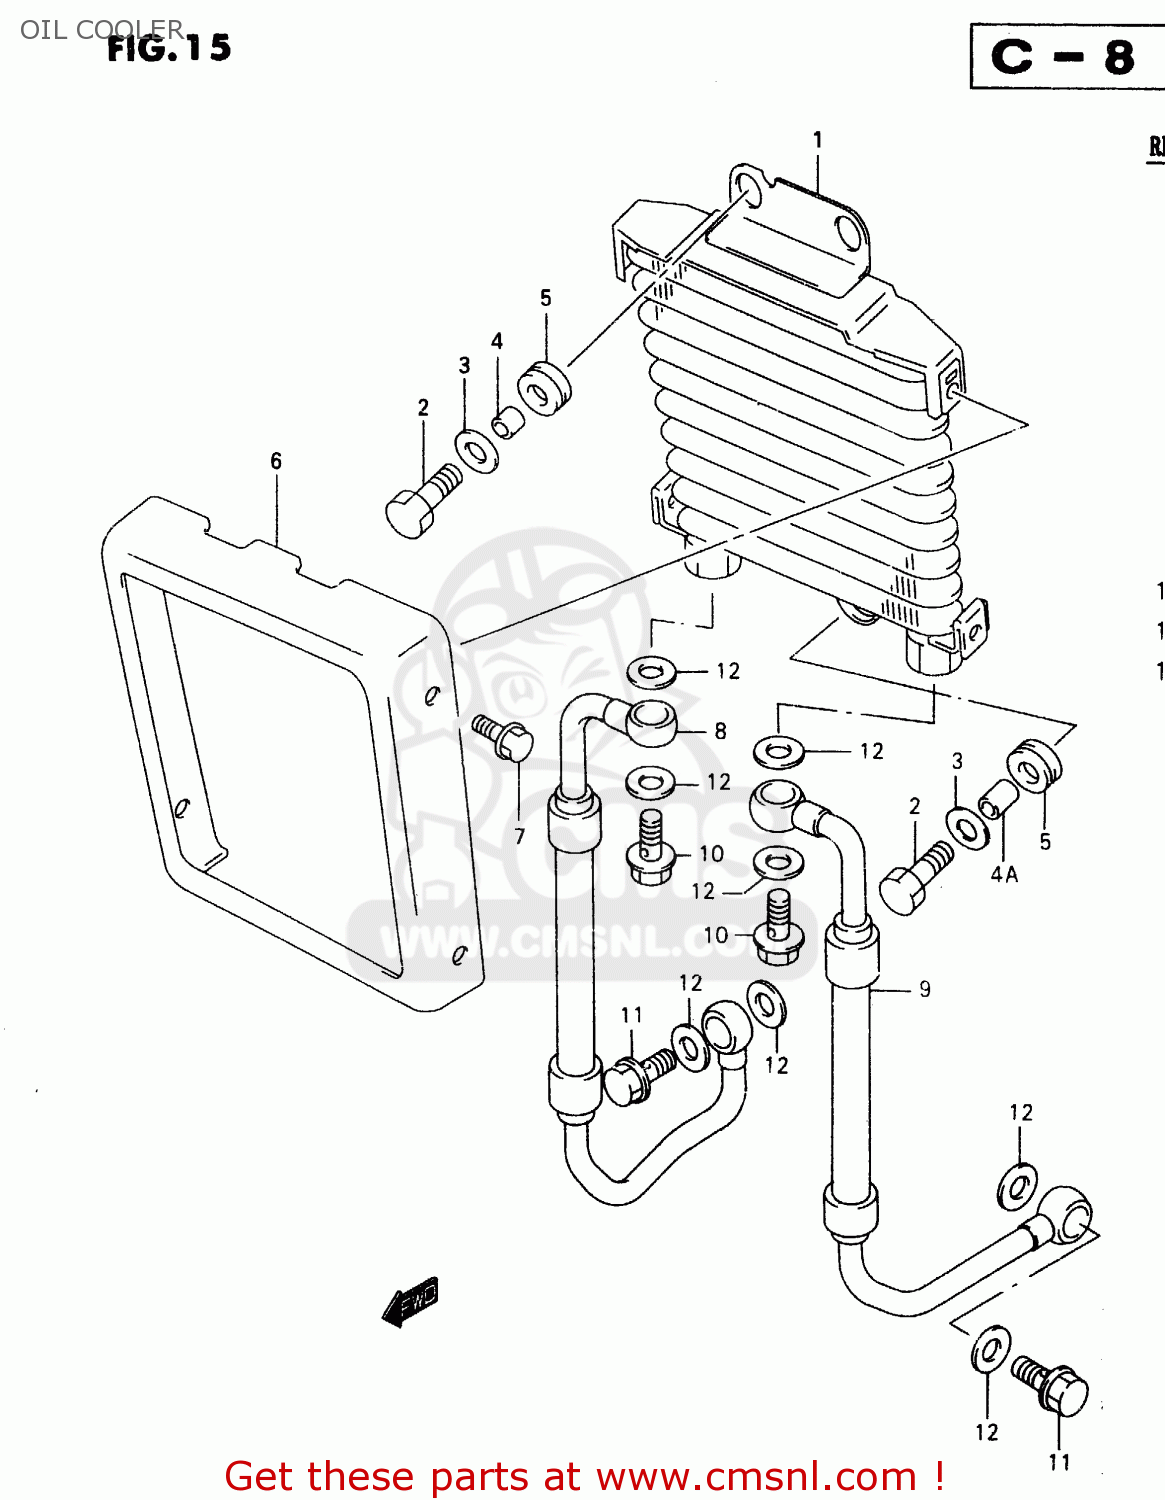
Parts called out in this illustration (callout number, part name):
1	COOLER ASSY,OIL
2	BOLT
3	WASHER(6.5X20X1.2)
4	SPACER(6.5X10X10)
4A	SPACER(6.5X10.5X12)
5	CUSHION
6	COVER,OIL COOLER
7	SCREW(6X12)
8	HOSE,OIL COOLER,RIGHT
9	HOSE,OIL COOLER,LEFT
10	BOLT UNION
11	BOLT UNION
12	GASKET(14X20X1.5) (NAS)
